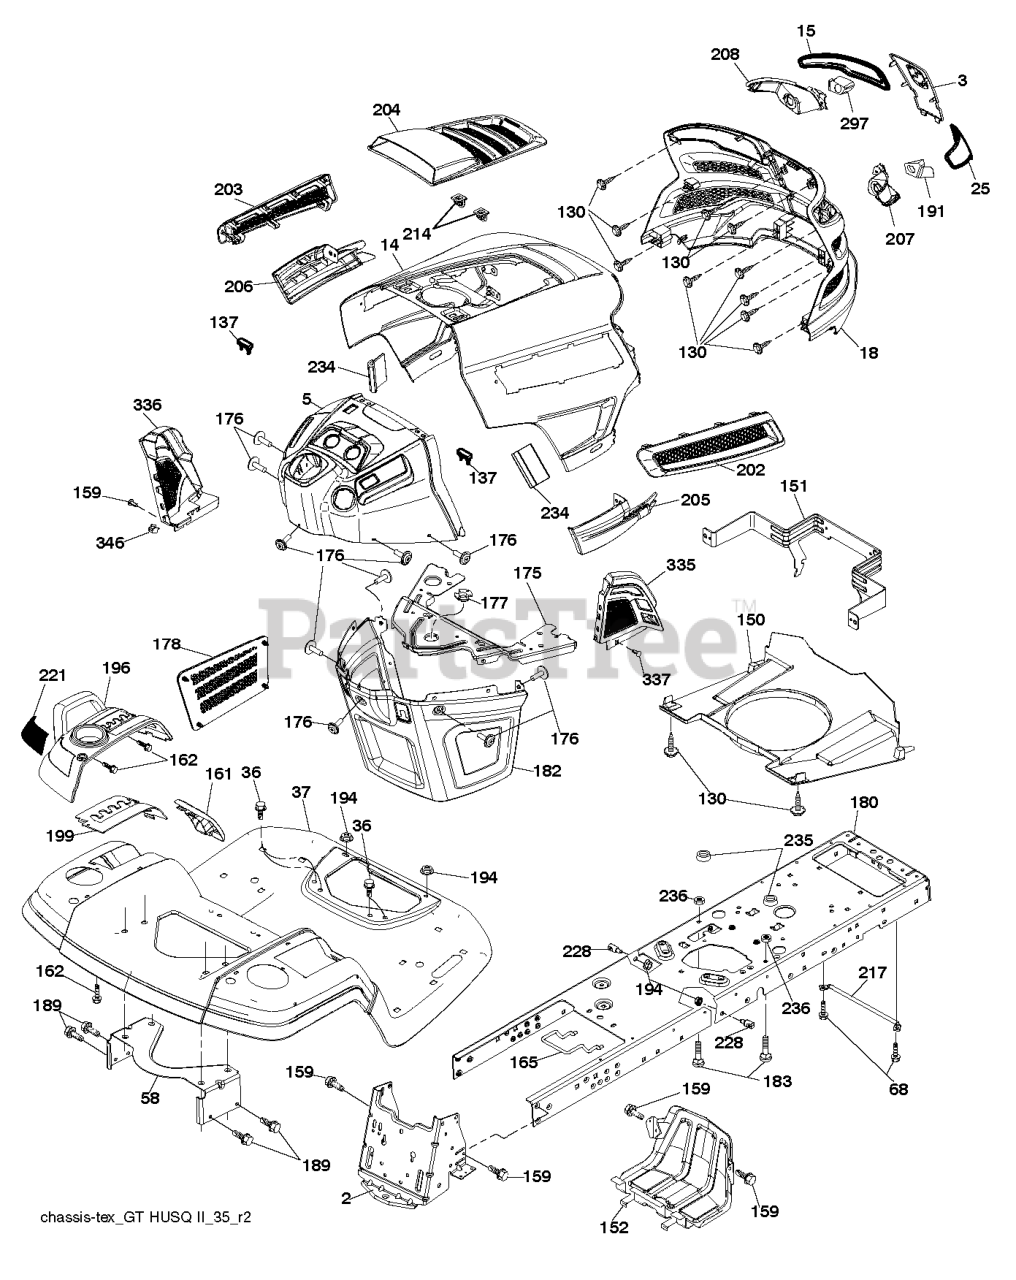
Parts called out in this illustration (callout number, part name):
2	DRAWBAR.STGT
3	APPLIQUE.SUBASM.GT.HUSQ.II
5	DASH.UPP.GT2.DUAL.RD.PTO.MCHOK
14	HOOD.ASM.HUSQVARNA.GT.TEX.422
15	LENS.HEADLIGHT.LH.GTII.2011
18	GRILLE.SUBASM.GT.HUSQ.II
25	LENS.HEADLIGHT.RH.GTII.2011
36	SCREW 5/16"
37	FENDER.PNT.TX.GT.CH/FW/DL.HUSQ
58	BRKT.SUPPORT.FNDR/TANK
68	SCREW LT
130	SCREW.#10 X 0.750.BOS
137	BUMPER DASH
150	AIR.DUCT.GTV.BLACK
151	BRACKET.PIVOT.HOOD.GT.HUSQ.II
152	SHIELD.BROWNING.PNT.GT.V2
159	SCREW, 3/8-16X3/4
161	CONSOLE.WINDOW.FUEL.HUSQ.GT
162	SCREW.HI-LO.CONSOLE
165	SUPPORT.TANK.REAR.B/TE
175	PLATE.CROSSMEMBER.HUSQ
176	SCREW.#10-24X5/8.RN.QU
177	BUSHING, STEERING
178	CARGO.ASM.NET.TXGT.W/C
180	CHASSIS.STAMPING.LT/GT
182	DASH.LOWER.COMMON.12V.ADAPTOR
183	BOLT.5/16-18X1-1/4 FULL THD
189	SCREW
191	INSERT.REFLECTIVE.RH.HUSQ.GTII
194	NUT LOCK HEX FLANGE 5/16-18
196	CONSOLE.ASM.DECKLIFT.HUSQGT.DL
199	PLATE.DECK.LIFT.HUSQVARNA.GT
202	VENT.SIDE.RH.GT.HUSQ.II.
203	VENT.SIDE.LH.GT.HUSQ.II.498
204	VENT.TOP.HUSQ.GT2
205	SIDE.TRIM.RH.GT.HUSQ.II
206	SIDE.TRIM.LH.GT.HUSQ.II.GRAY
207	BEZEL LIGHT.RH.GT.II.MYLAR
208	BEZEL LIGHT.LH.GT.II.MYLAR
214	CLIP.RETAINER.TINNER.
217	ROD.PIVOT.HOOD
221	REFLECTOR.LH.TEX GT HU
228	STUD.FASTNER.W/ANTI-ROTATE
234	BUMPER.HOOD.TEX.HUSQVARNA
235	SPACER FENDER
236	NUT.CENTERLOCK.5/16-
297	INSERT.REFLECTIVE.LH.HUSQ.GTII
335	COVER.RH.CLOSE.OUT.BLACK
336	COVER-LH.LOWER.DASH.GT2.BLACK
337	CLIP.XMAS.TREE.ITW.2622-00
346	CLIP,INSULATOR
